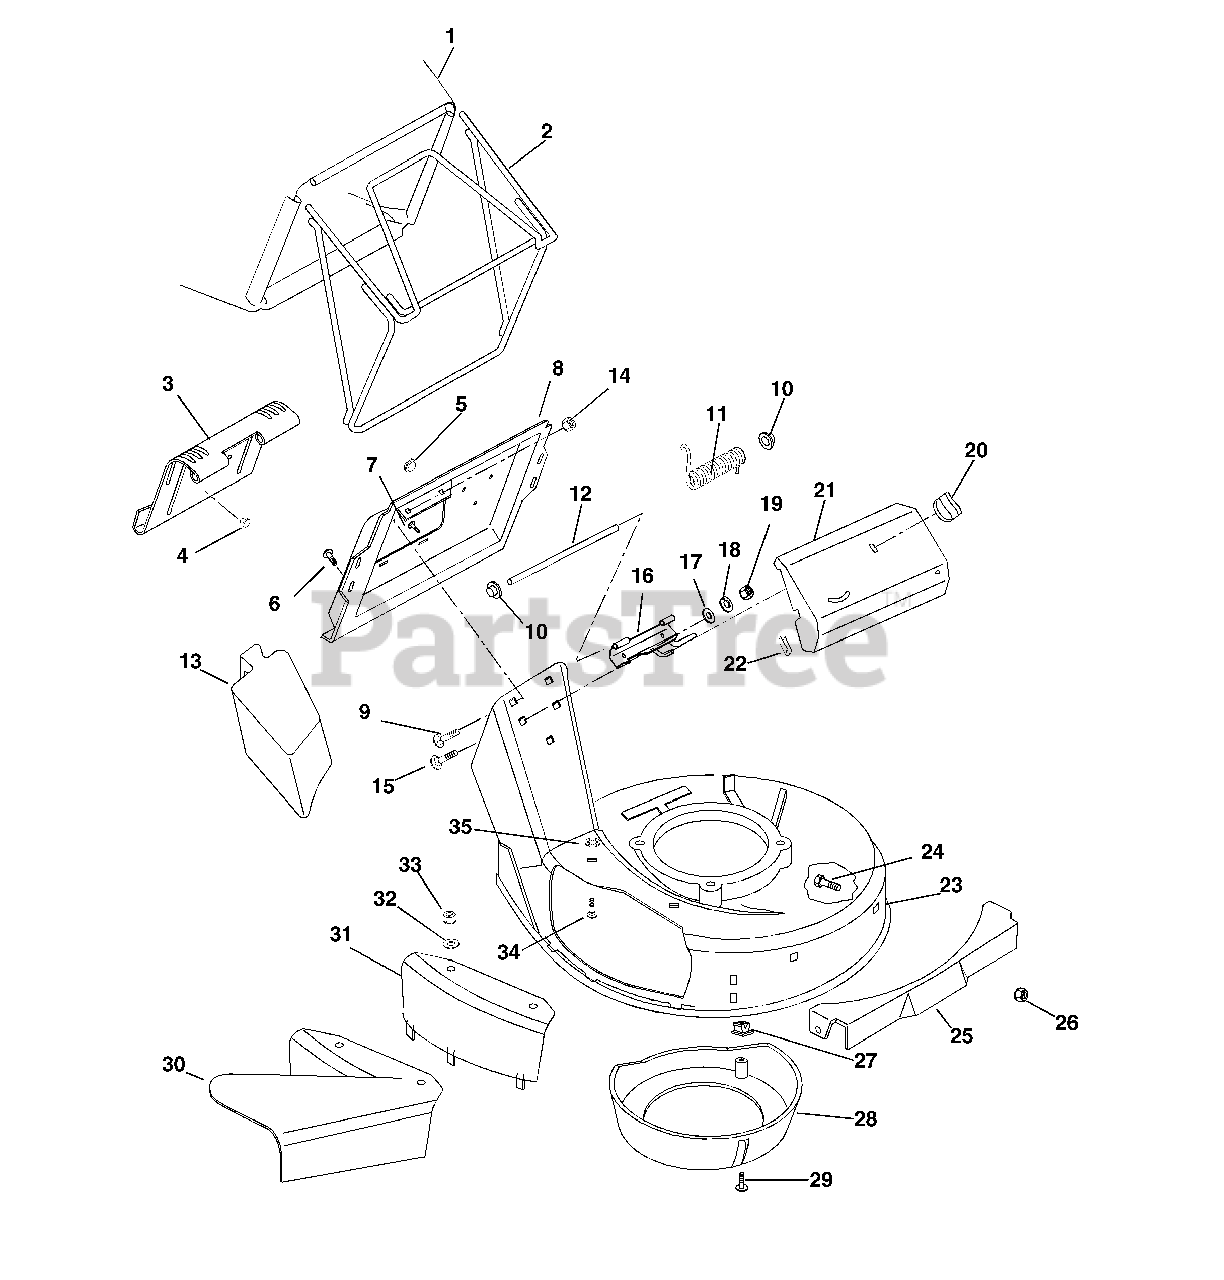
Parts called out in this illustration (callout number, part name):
1	BAG, GRASS MACK
2	FRAME, BAGGER
3	CATCHER PLATE DOOR
4	BUTTON BUMPER
6	@SCR-TAP 12-24X.50 HWH TR YWZC
7	SCR-TAP 10-24X.375 TORX PHD YZ
8	CATCHER PLATE
9	@BLT-RHDSSQNK .25-20X.38 G2YZ
10	PUSH NUT, .25
11	SG-TORS .120X.68X3.09
12	DOOR PIN
13	MULCH MASTER MULCHER ACCESSORY
14	@NUT-SPNLK-FLG .25-20 YWZC
15	@BLT-RDHDSQNK .25-20X.75 G5YZ
16	HINGE BASE WELDMENT
17	WSHR-FL-STL .328X.87X.179 YWZC
18	WSHR-LK .250X.077 HVY YWZC
19	@NUT-HEX .25-20 YWZC
20	WING - NUT
21	COVER, DRIVE
22	TRIM BUMPER
23	MOWER PAN W/SFTY DCLS MACK SP
24	@BLT-RDHDSQNK .31-18X.50 G5YZ
25	PANEL, FRONT
26	@NUT-LK-CTR .31-18 YWZC
27	PLASTIC GROMMET
28	CENTER BAFFLE
29	SCR-TAP 10-16X.62 SLPH AB YWZC
30	SIDE DISCHARGE ASSEMBLY
31	COVER, SIDE DISCHARGE
32	@WSHR-FL-STL.406X.812X.065 YWZ
33	@NUT-LK-NYL .312-18 YWZC
34	BLT-RDHDSQSHK.31-18X.75 GR2 YW
35	NUT-PUSH .312
